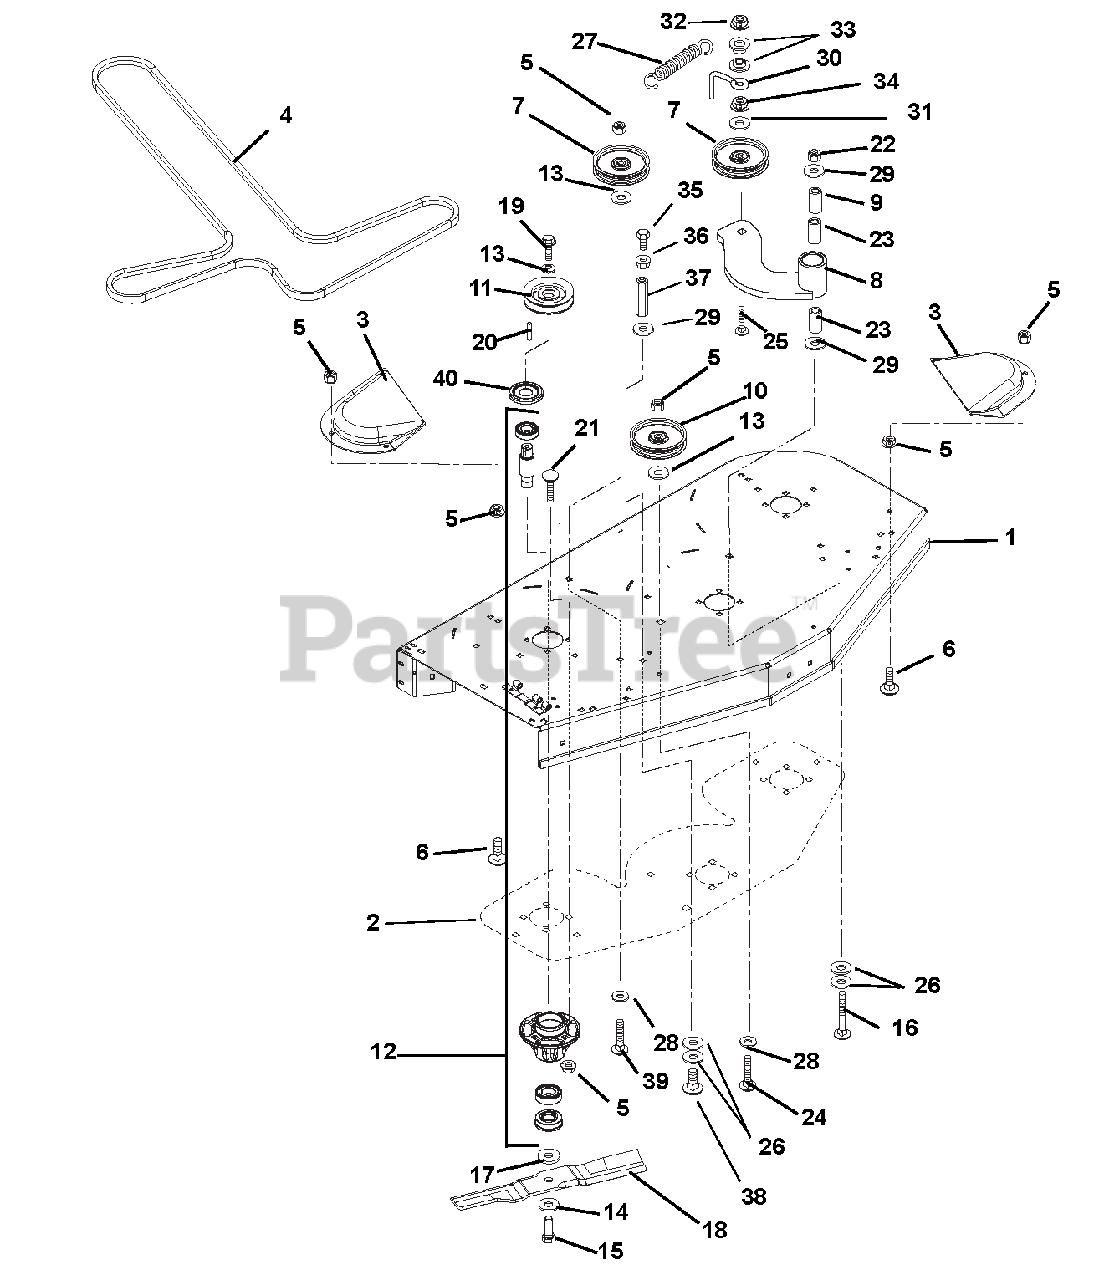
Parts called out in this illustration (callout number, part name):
1	WMT, 40" DECK
1	WMT, 44" DECK
1	WMT, 48" DECK
2	PLATE, 40" DOUBLER
4	V-BELT, HA-WRAPPED
4	BELT,HA WRAPPED
5	@NUT-LK-NYL-FLG .38-16 YWZC
6	@BLT-RDHDSQNK .38-16X1.25 G5YZ
7	IDLER, FLAT .38X4.00X1.06
8	WMT, IDLER ARM
9	BSHG, SPCR .502X.997X2.03 PM
10	PULLEY, IDLER 4.00
11	SHEAVE, SPINDLE - 4.25 DIA.
11	SHEAVE, SPINDLE - 4.50 DIA.
11	SHEAVE, 4.25 DIA A-SECTION
12	ASSEMBLY, SPINDLE
13	WSHR,FLT STL.406X1.50X.245YWZC
14	WSHR-BLVL .669X1.535X.138
15	BLT-HEX .62-18X1.75 GR8 YWZC
16	@BLT-RDHDSQNK .50-13X3.50 G5YZ
17	WSHR-FLT .640X1.75X.250 YWZC
18	MOWER BLADE, 13.94"
18	BLADE, 15.50"
18	BLADE, MOWER (16.19")
19	BLT-HEX .38-16X1.00 YZ GR8
20	KEY, SQ .25 X .38 X .25
21	@BLT-RDHDSQNK .38-16X1.50 G5YZ
22	@NUT-LK-TOP-FLG .50-13 YWZC
23	BRG, 1.00 X 1.12 X .75
24	@BLT-RDHDSQNK .38-16X2.00 G2YZ
25	@BLT-RDHDSQNK .38-16X3.00 G5YZ
26	WSHR-FL-STL.755X1.375X.062YWZC
27	EXTENSION SPRING
28	@WSHR-FL-STL.563X1.38X.109YWZC
29	WSHR-FL-STL .515X1.625X.250 YZ
30	BELT FINGER
31	WSHR-FL-STL .406X1.00X.188 YWZ
32	@NUT-LK-TOP-FLG .38-16 YWZC
33	BSHG-FLG .406X.88X.270X.140
34	NUT-SPIRALOCK-FLG .50-13 PLN
35	@BLT-HEX .50-13X2.00 GR5 YWZC
36	@NUT-HEX .50-13 YWZC
37	NUT, COUPLING 1/2-13X1.75 YWZC
38	@BLT-RDHDSQNK .50-13X1.25 G5YZ
39	@BLT-RDHDSQNK .38-16X2.75 G5YZ
40	DUST CAP
